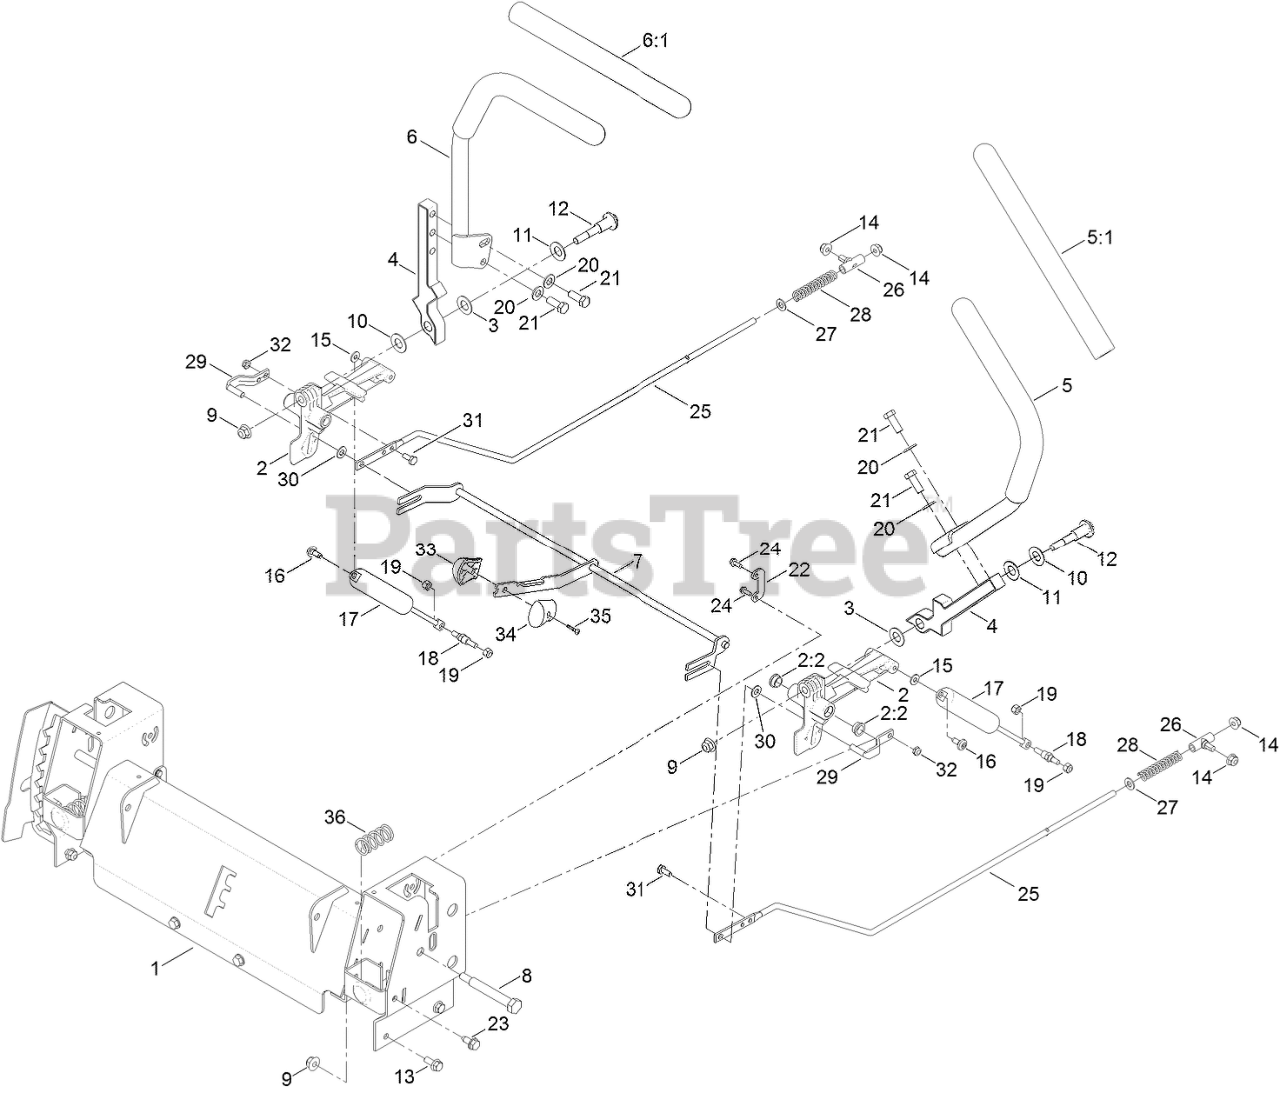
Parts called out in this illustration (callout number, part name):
1	CONTROL BOX ASM
2	ACTUATOR ARM ASM
2:2	BUSHING-FLANGE
3	WASHER-NYLON
4	LEVER-CONTROL
5	HANDLE-CONTROL, LH
6	HANDLE-CONTROL, RH
7	SPEED CONTROL ASM
8	BOLT-PIVOT
9	NUT-HF, NI
10	WASHER
11	WASHER-BELLEVILLE
12	BOLT-PIVOT
13	SCREW-HHF
14	NUT-HF, NI
15	WASHER
16	SCREW-SHOULDER
17	DAMPER
18	STUD-DAMPER
19	NUT-LOCK, NI
20	WASHER-FLAT
21	SCREW-HH
22	RETAINER
23	SCREW-HWHTF
24	SCREW-TAPTITE
25	ROD-HYDRO
26	MOUNT-ROD, HYDRO
27	WASHER-PLAIN
28	SPRING-RETURN, NEUTRAL
29	PIN-ROD, HYDRO
30	SPACER-NYLON
31	SCREW-HH
32	NUT-LOCK, NI
33	KNOB-RH
34	KNOB-LH
35	SCREW-PPH
36	SPRING-RETURN
